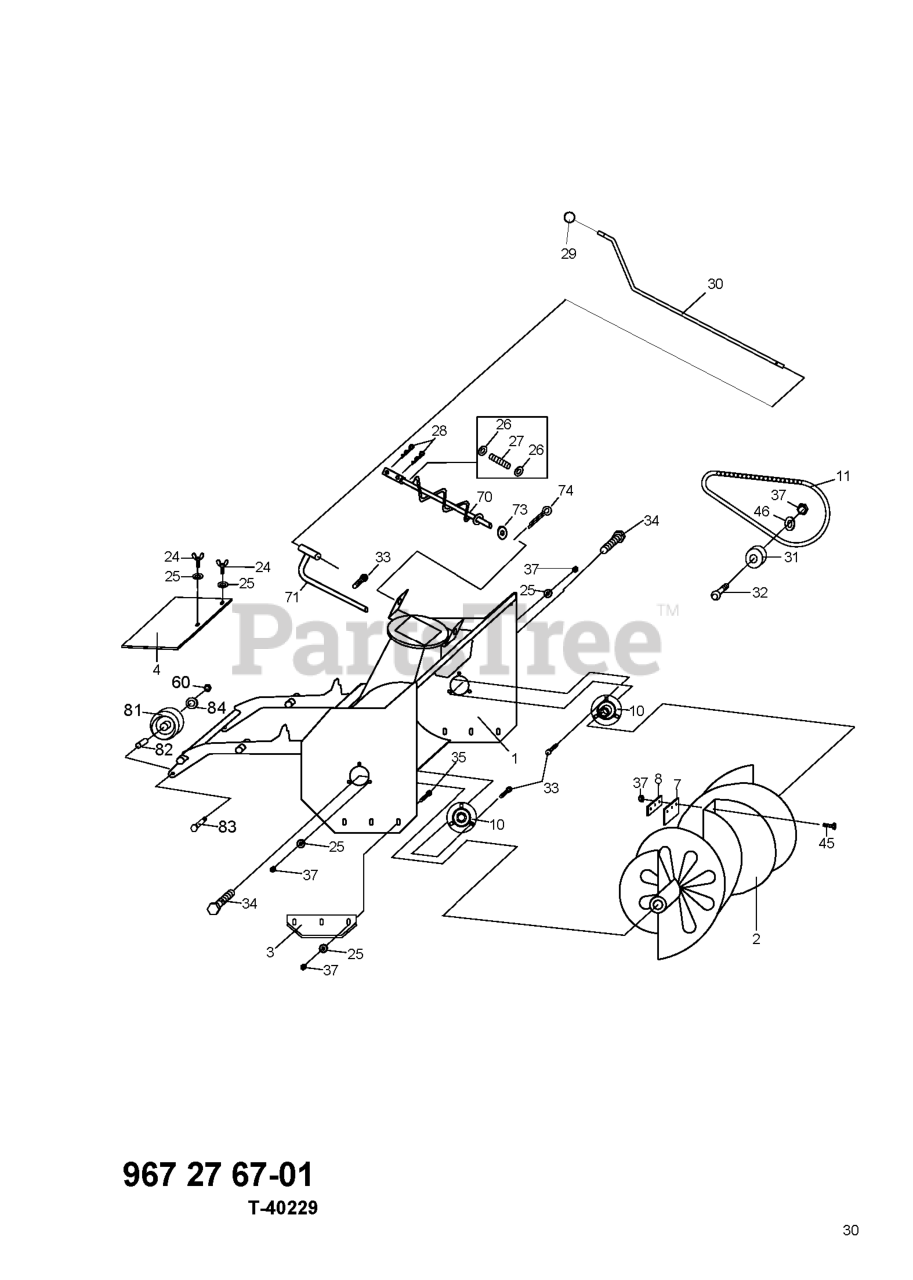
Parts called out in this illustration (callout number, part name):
7	PROTECTION
28	PIN RETAINING SCREW
31	CHAIN TENSIONER
74	PIN RETAINING SCREW
81	SUPPORT WHEEL
82	COLLAR
